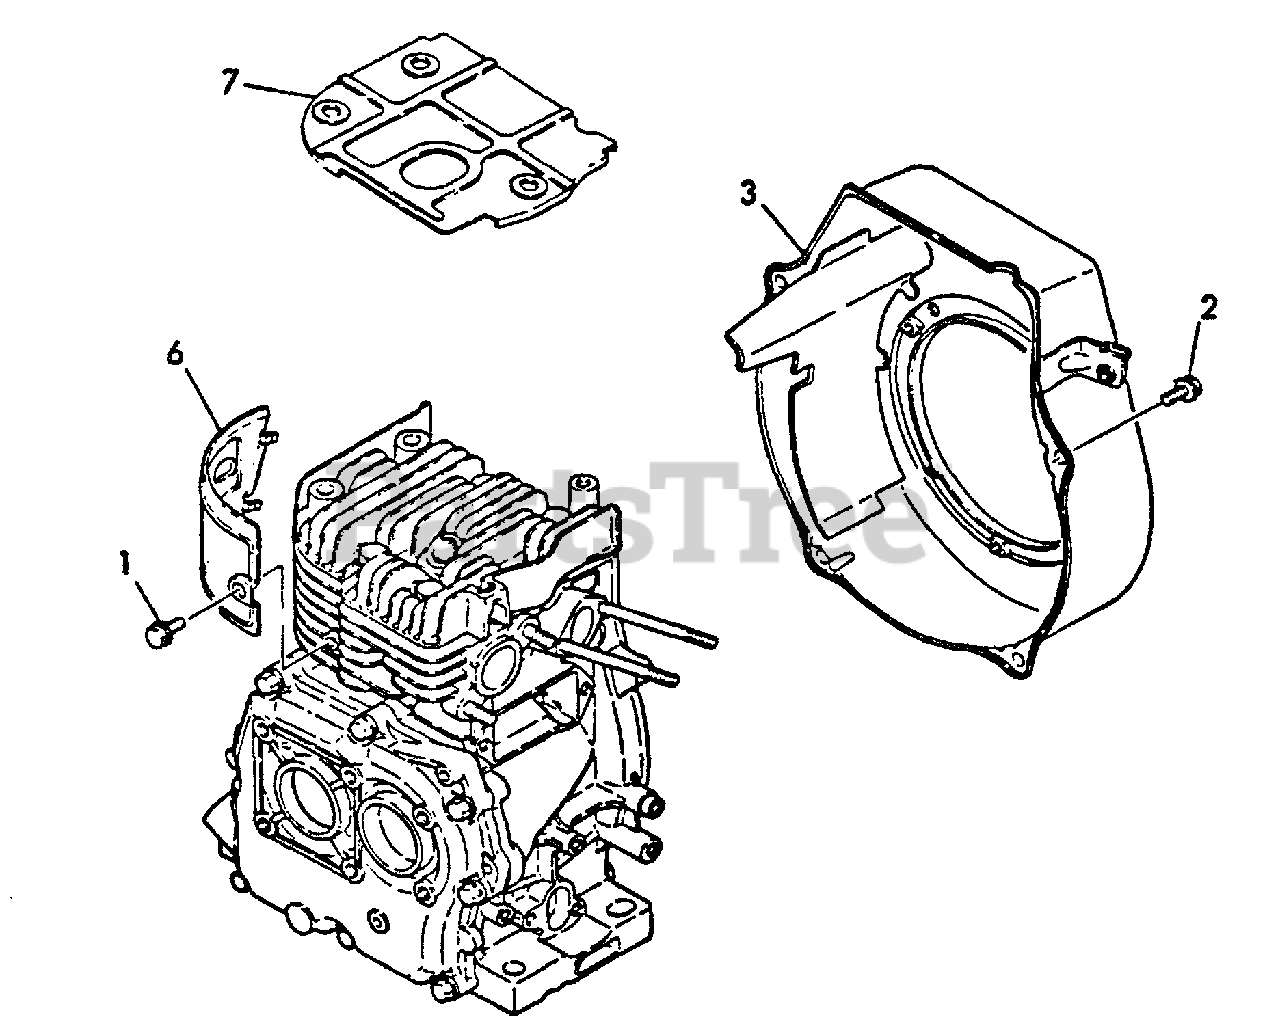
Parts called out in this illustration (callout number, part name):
1	BOLT - 6×8 -- PLATED
2	BOLT - 6×8 -- PLATED
3	COVER, FAN
6	PLATE
7	COVER, HEAD
